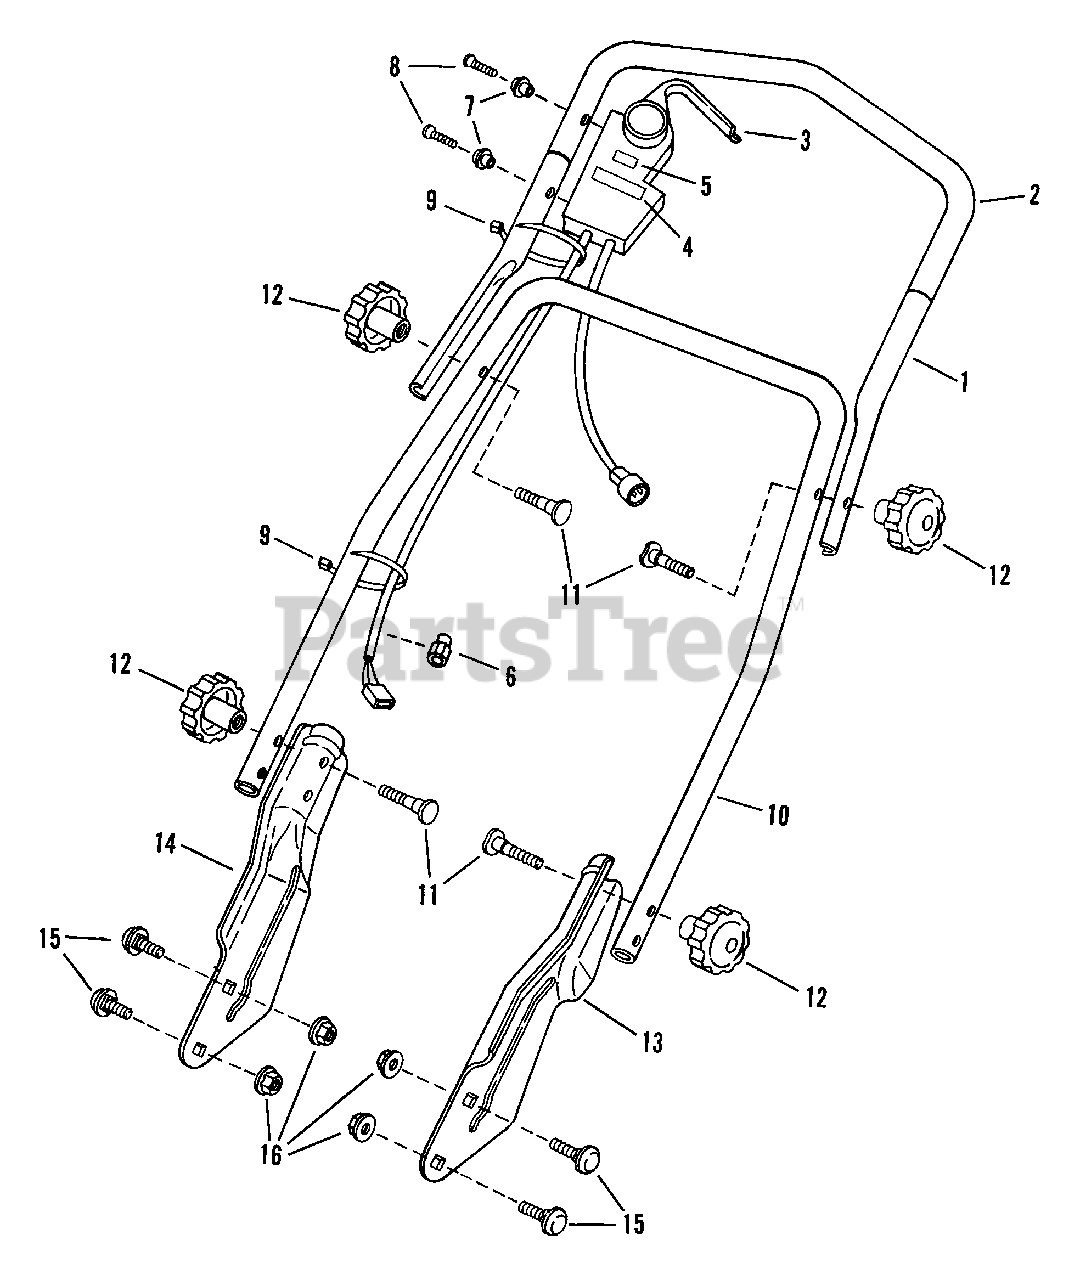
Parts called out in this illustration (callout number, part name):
1	ASSEMBLY Upper Handle
2	TUBING, Heat Shrink
3	CONTROL, Electric
4	DECAL, Starting Procedure
5	DECAL, Circuit Breaker Reset
6	STRAIN-RELIEF, Harness
7	INSULATOR, Handle
8	SCREW, #10-24 x 1-3/8" Slotted Cap
9	TIE, Cable
10	HANDLE, Middle
11	SCREW, 5/16-18 x 2" Curved Head
12	KNOB, 5/16-18
13	HANDLE, Lower L.H.
14	HANDLE, Lower R.H.
15	BOLT, 5/16-18 x 5/8" Short Neck Carriage
16	NUT, 5/16-18 Hex Flange Lock
